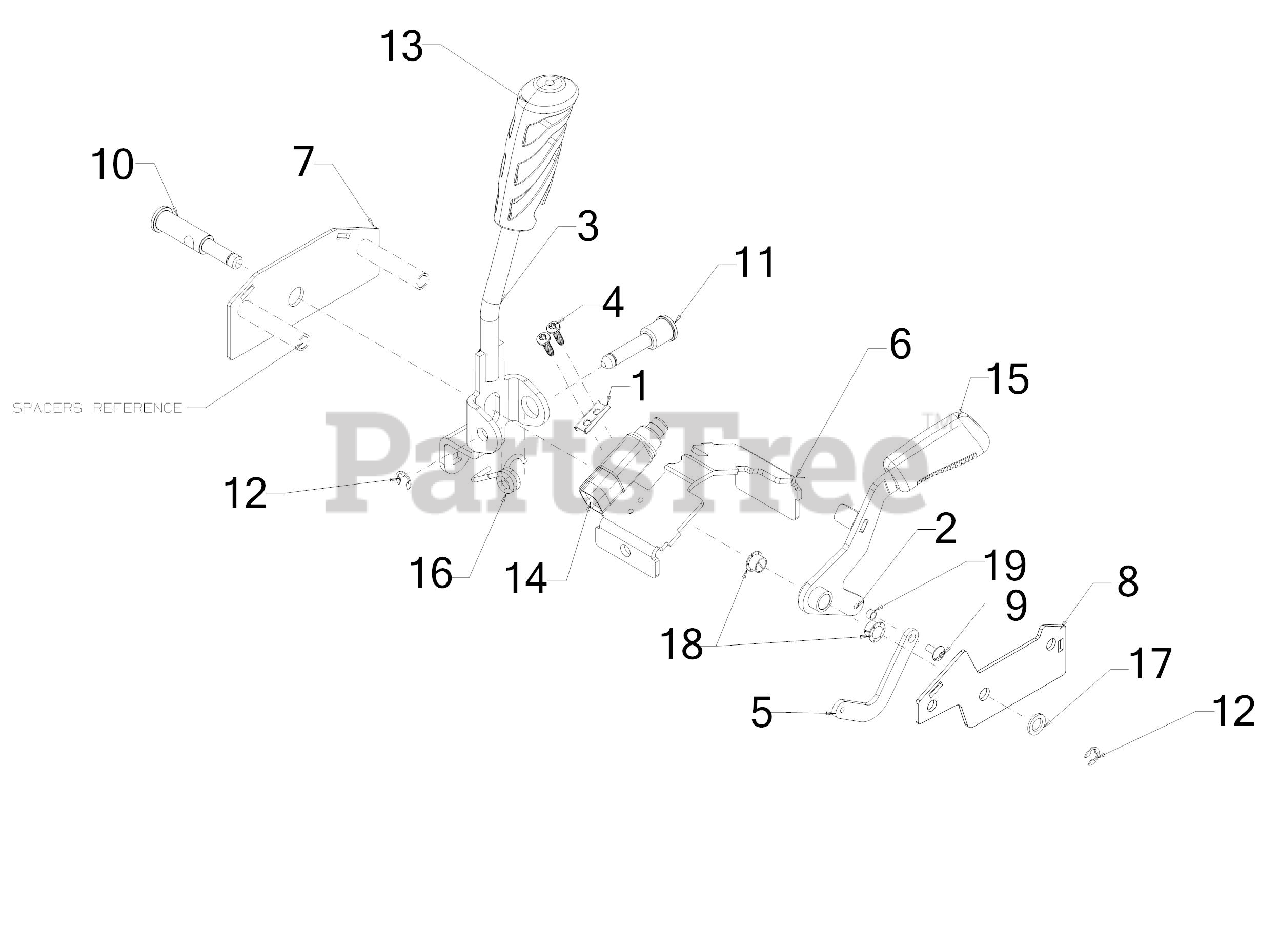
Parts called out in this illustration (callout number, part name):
1	PLATE-SWITCH
2	DIFFERENTIAL HANDLE ASSEMBLY
3	SHIFT HANDLE ASSEMBLY
4	SCREW #10-24X11/16:T25
5	LINK BRACKET
6	TOP HOUSING SHAFT BRACKET
7	HOUSING SHAFT BRACKET (LH)
8	HOUSING SHAFT BRACKET (RH)
9	SCREW-#10-24 x .400 SELF TAP
12	EXTERNAL RETAINING RING 7MM
14	SEALED PLUNGER SWITCH
15	BRAKE HANDLE GRIP
16	TORSION SPRING
17	FLAT WASHER
18	FLANGE BEARING
19	OIL TUBE SLEEVE
